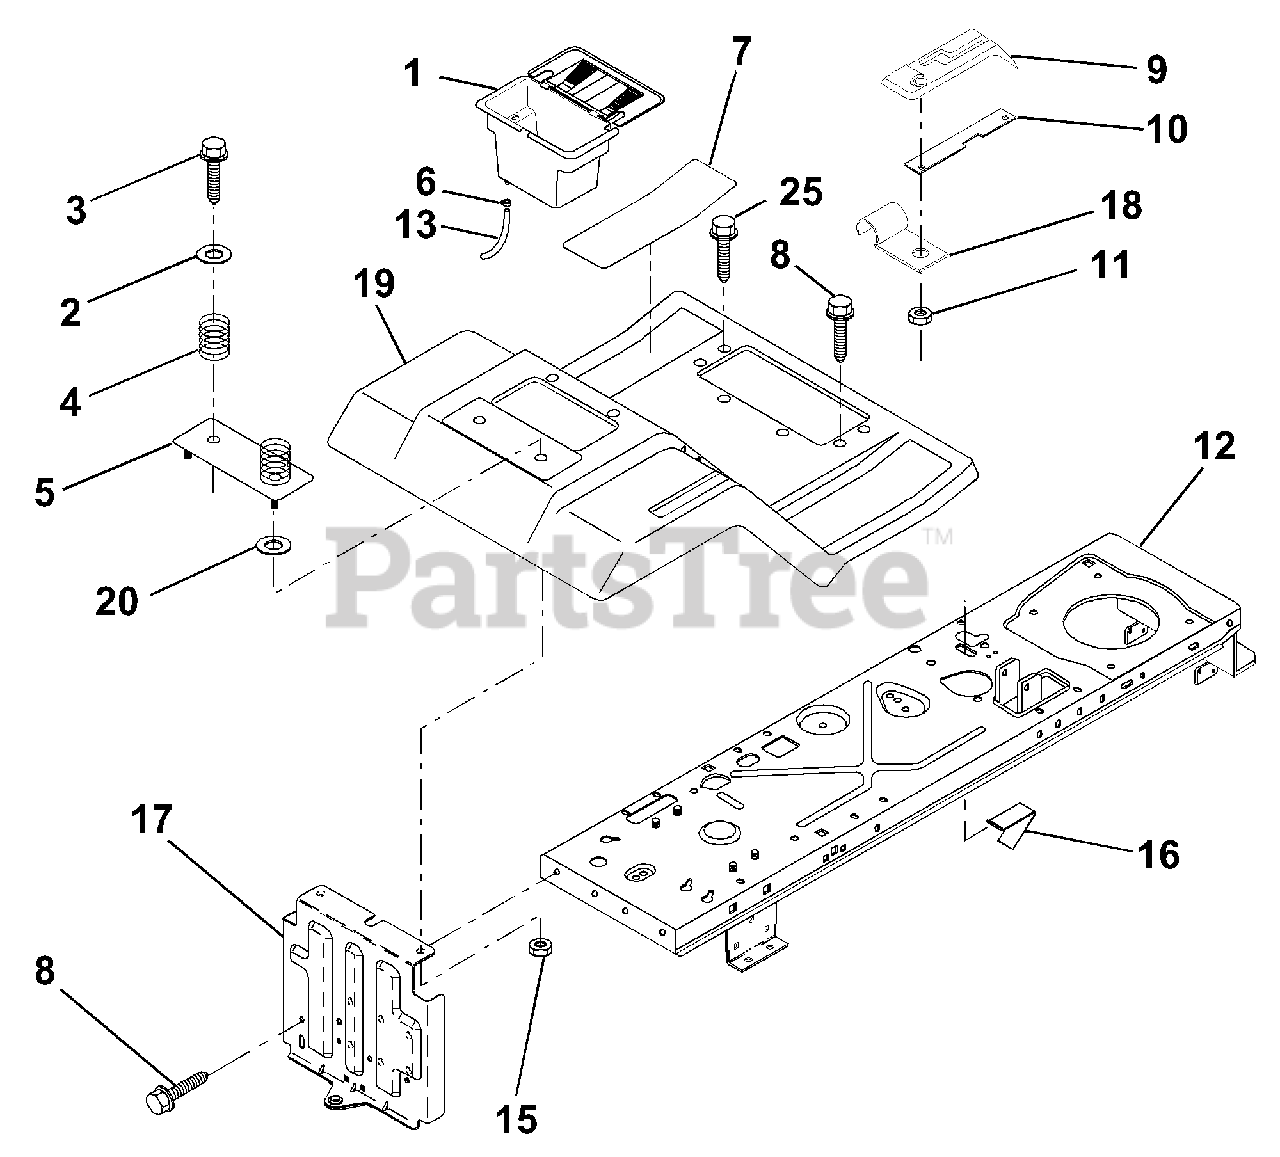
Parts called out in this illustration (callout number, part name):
1	Case, Battery
2	Washer 13/32 x 1-1/4 x 12 Ga.
3	Screw, Hex Wsh. Thrdrol 3/8-16 x 3/4
4	Spring, Compression, Seat
5	Plate, Asm. Battery
6	Clamp, Hose
7	Pad, Footrest
8	Screw Thdrol 5/16-18 x 3/4
9	Console, Shift Control
10	Bar, Shift Lock
11	Nut, Self-Threading, Wsher Hd 3/16
12	Assembly, Frame
13	Tube, Battery Drain
15	Nut, Keps 1/4-20 UNC
16	Switch Actuator
18	Clip, Insulated
19	Fender/Footrest
20	Washer 9/32 x 7/8 x 13 Ga.
25	Scr-Hx Wsh Thd Rol 5/16-18 x 1
